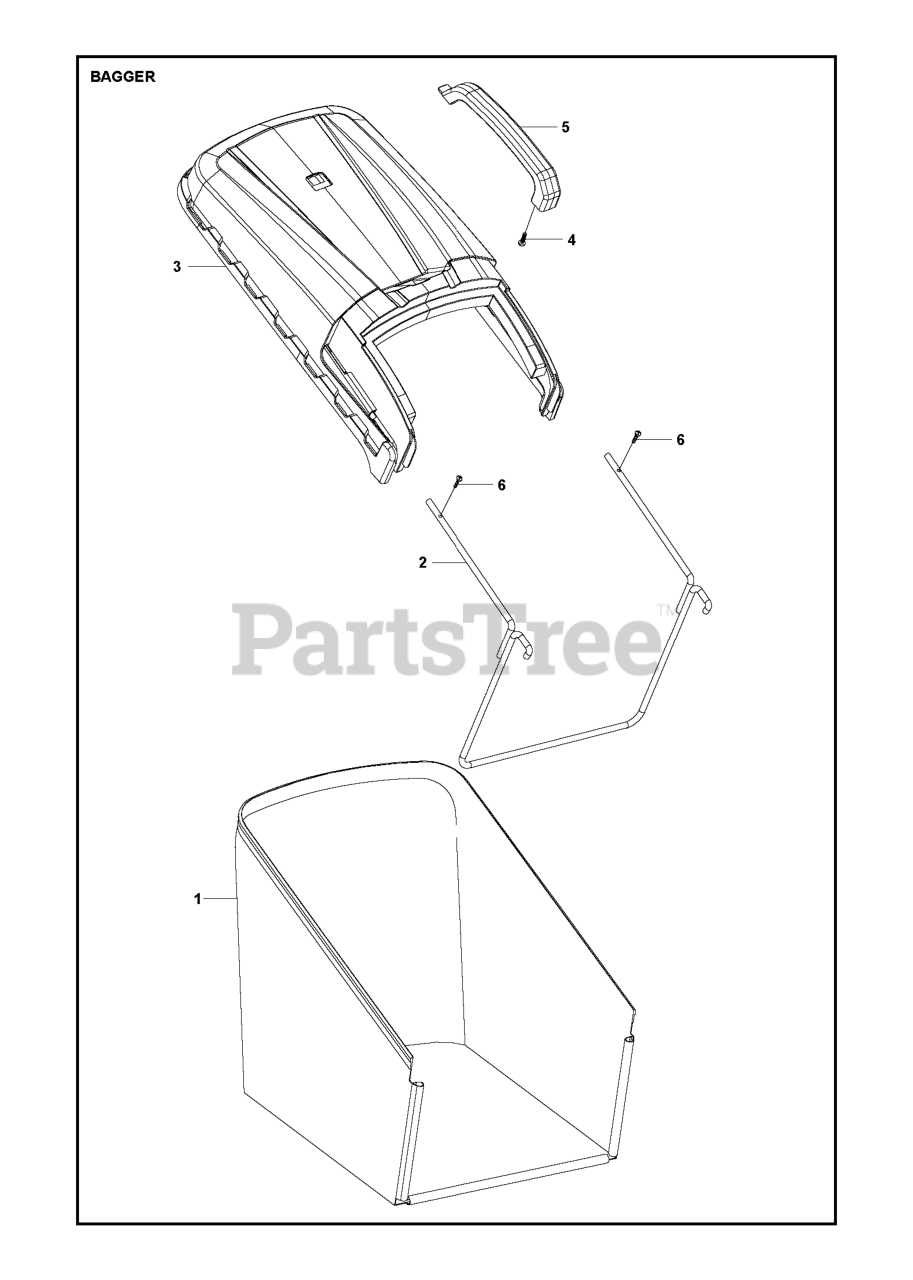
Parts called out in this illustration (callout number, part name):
1	GRASSBAG #25100173001
2	BRACKET #26300299201
3	COVER GRASS CATCHER #253417001
4	SCREW ST4.8*19,GB845 #26800104
5	HANDLE #25341800101
